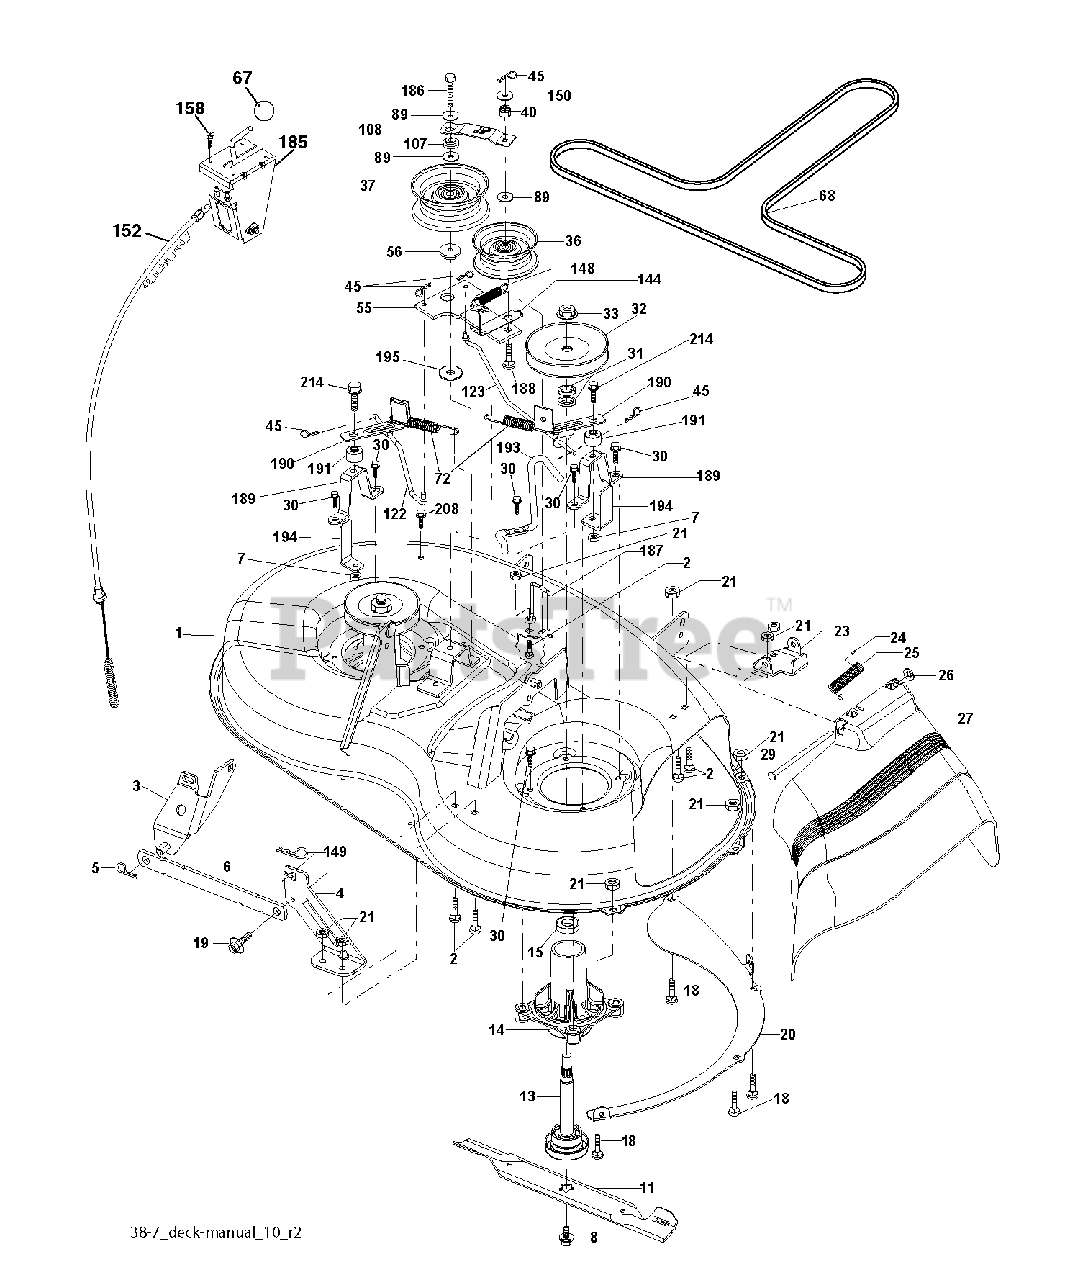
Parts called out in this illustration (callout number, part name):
1	DECK.WELDMENT.38"2005
2	BOLT
3	BRKT ASM SWAY BAR
4	BRACKET DECK SWAY BAR 38"/42"
5	RETAINER-SPRNG RB
6	BAR SWAY DECK
7	NUT.71038.31-18.HEX.NYLOCK
8	BOLT.WASHER.ASM.7/16-2
11	BLADE 38" PREMIUM
13	SHAFT.ASM.MDRL.N/GREASE.38
14	HOUSING MANDREL
18	BOLT
19	BOLT SHD 5/16-18
20	BAFFLE VORTEX
21	LOCKNUT
23	BRKT.DEFLECTOR.38"2005+
24	CAP-SLEEVE LT
25	SPRING.TORSION.DEFLECT
26	NUT PUSH M
29	ROD.HINGE
30	SCREW, WASHER HEAD
31	WASHER.SPACER.MANDREL
32	PULLEY MANDREL
33	NUT.FLANGE.LOCK.TOP
36	FLAT IDLER PULLEY
37	PULLEY.IDLER.FLAT.UNPLATED
40	LOCKNUT
45	RETAINER M
55	IDLER ARM
56	SPACER.RETAINER.MOWER
67	KNOB T (3/8 HOLE)
68	V-BELT.MOWER.38"2005+
72	SPRING.BRAKE.RETURN.38"
89	WASHER
107	SPACER.IDLER.ARM
108	STIFFENER.IDLER.ARM
122	ROD, BRAKE LH LINK
123	LINK.BRAKE.38"RIGHT
144	KEEPER BELT
148	IDLER RETURN SPRING
149	SPRING.RETAINER.YELLOW.ZINC
150	WASHER LT
152	CABLE.CLUTCH.38".SERVICE
158	SCREW
185	HEAD ASM. CABLE CLUTCH
186	SCREW.HXWSH.3/8
187	KEEPER BELT
188	BOLT, CARRIAGE IDLER
189	STAND, BRAKE
190	ARM, BRAKE
191	SPACER, BRAKE
193	KEEPER BELT RH MANDREL
194	GUARD BRAKE
195	WASHER 12/32X2X10GA
208	SCREW 3/8-16X1/2
214	BOLT/WASHER ASM 5/16-18
